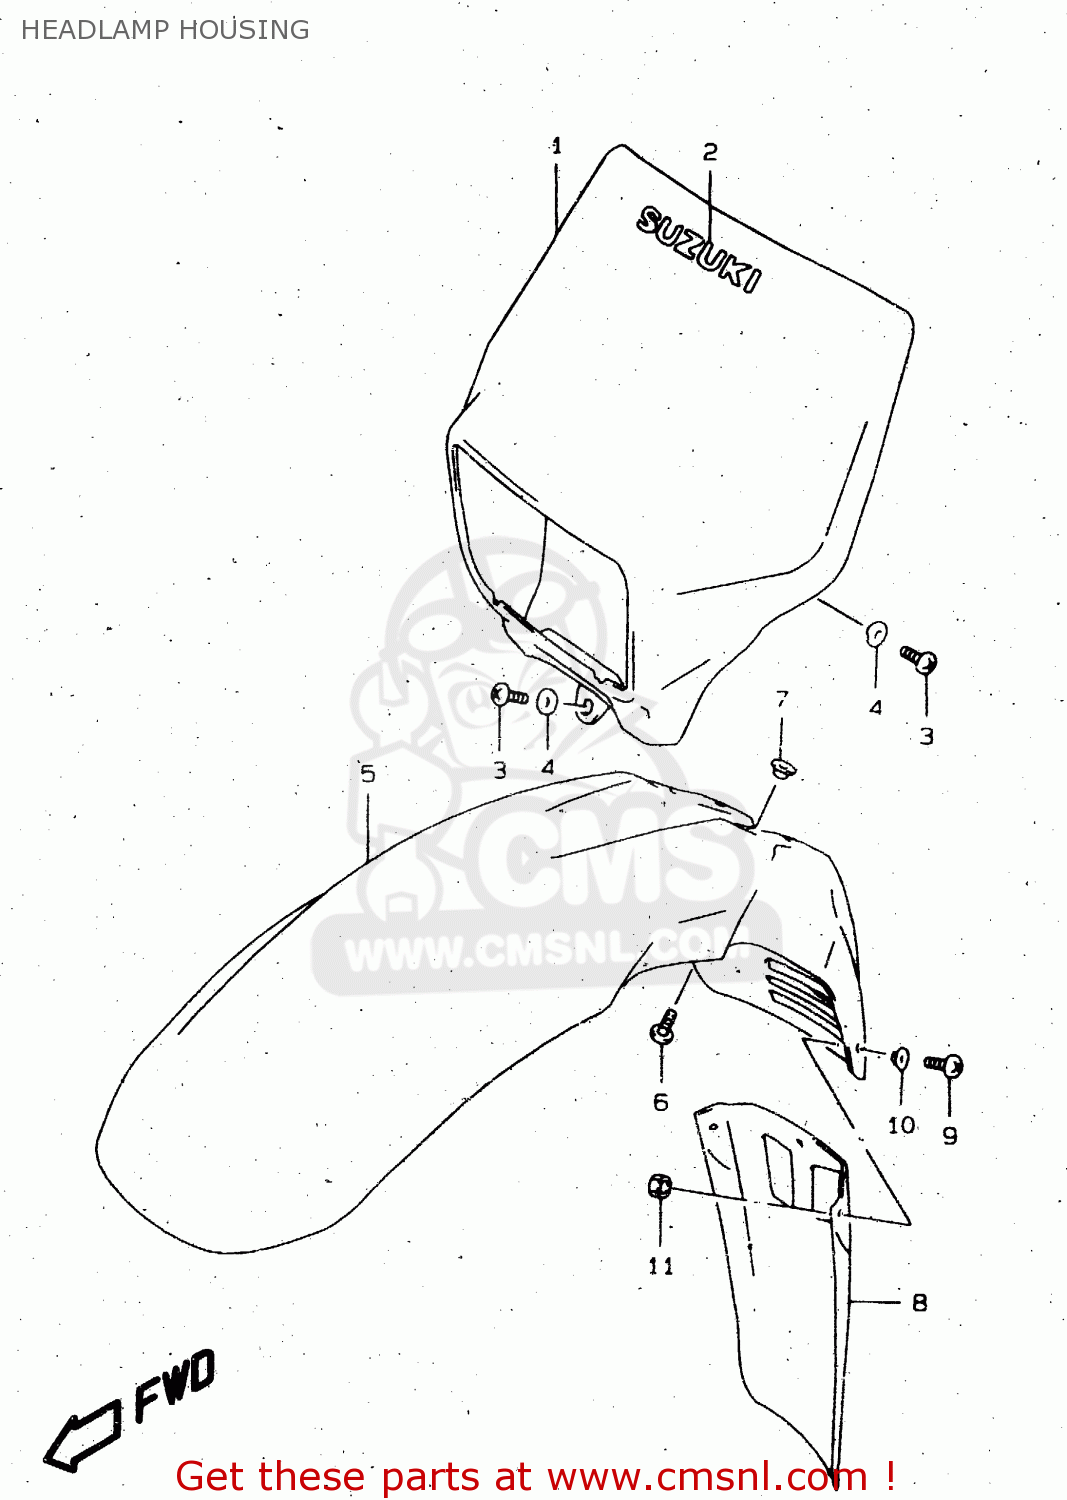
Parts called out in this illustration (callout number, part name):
1	COVER,HEADLAMP
2	EMBLEM
3	SCREW 6X12
4	WASHER
5	FENDER,FR
6	BOLT(6X16)
7	WASHER
8	MUDFLAP,FR FENDER
9	SCREW
10	WASHER(5.5X16X1.2)
11	NUT
